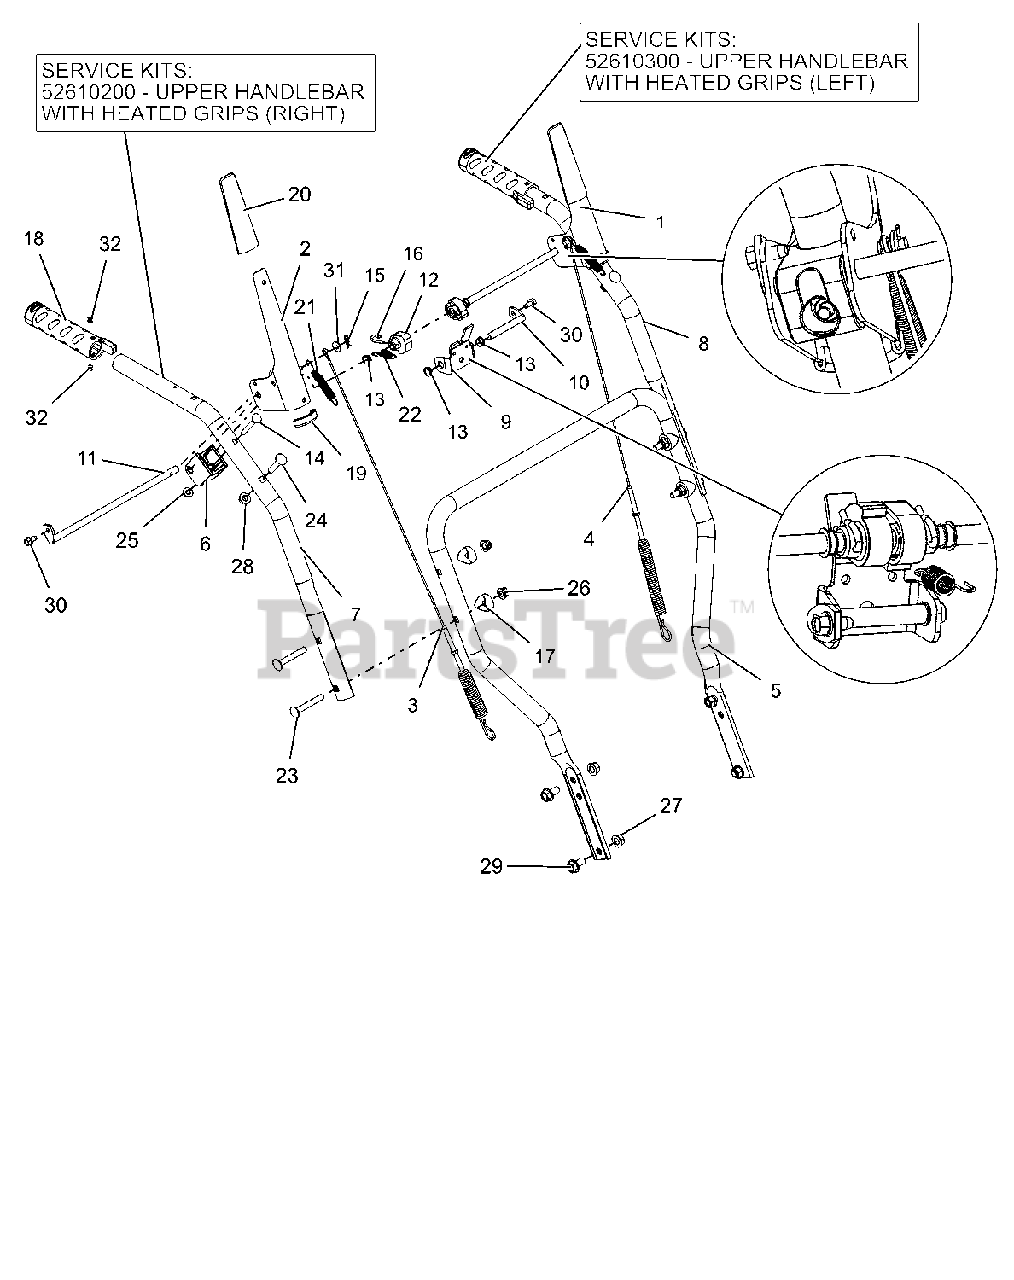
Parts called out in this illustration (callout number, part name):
1	LEVER, CLUTCH-LH
2	LEVER, CLUTCH-RH
3	CABLE, AUGER (DELUXE & PRO)
4	CABLE, UPPER TRACTION
5	HANDLEBAR, LOWER
6	BLOCK, CLUTCH PADDLE
7	HANDLEBAR, UPPER - RH
8	HANDLEBAR, UPPER - LH
9	BRACKET, INTERLOCK ARM
10	ROD, PIVOT - INTERLOCK
11	ROD, PADDLE MOUNT - PRO
12	CAM, INTERLOCK
13	BUSHING, POLYLINER-.38 SNAPIN
14	BLT-RDHDXLSQNK .25-20X2.0 G5YZ
15	PIN-HAIR INT .06X.18X.77
16	PIN, SPRING CLIP
17	SPACER, HANDLEBAR
18	GRIP,HEATED HANDLE-GRAY
19	EDGING, CLUTCH PADDLE - 2.00"
20	SLEEVE, CLUTCH PADDLE-GRAY
21	SPRING, EXTENSION
22	SPRING-EXT .047X.438X1.45
23	@BLT-RDHDSQNK .31-18X2.25 G5YZ
24	@BLT-RDHDSQNK .31-18X1.50 G5YZ
25	@NUT-LK-CTR-FLG .25-20 YWZC
26	@NUT-LK-NYL-FLG .31-18 YWZC
27	@NUT-LK-TOP-FLG .38-16 YWZC
28	@NUT-LK-TOP-FLG .31-18 YWZC
29	BLT-SERHFWH .38-16X.75 YWZC
30	SCR-TAP .25-20X.50 HWH TR YWZ
31	@WSHR-FL-STL.281X.62X.065 YWZC
32	RVT-POP #43 .125X.313 STL ZINC
33	HANDLEBAR, UPPER RH W/HW
34	HANDLEBAR, UPPER LH W/HW
